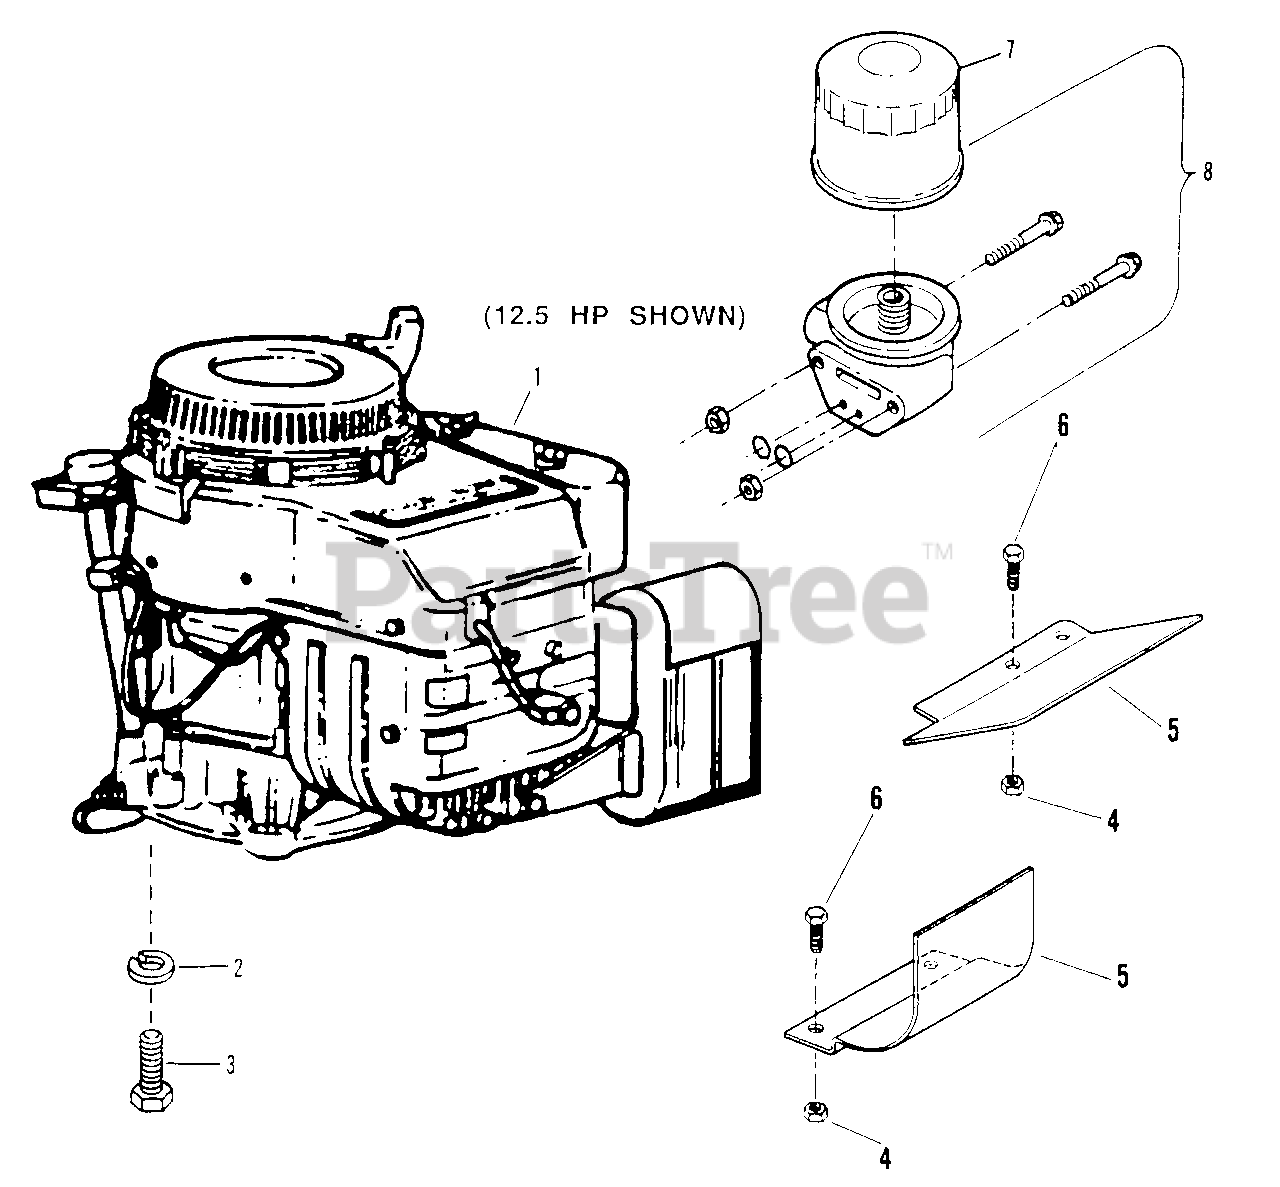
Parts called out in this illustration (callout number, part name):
2	LOCKWASHER, 5/16" split
3	BOLT, M8 1.25 x 25 Tap Grade 5
4	NUT, 5/16C ESNA Hex Lock
5	SHIELD, Heat
6	CAPSCREW, 5/16C x 3/4" Hex Head
7	FILTER, Oil
8	KIT, Oil Filter
